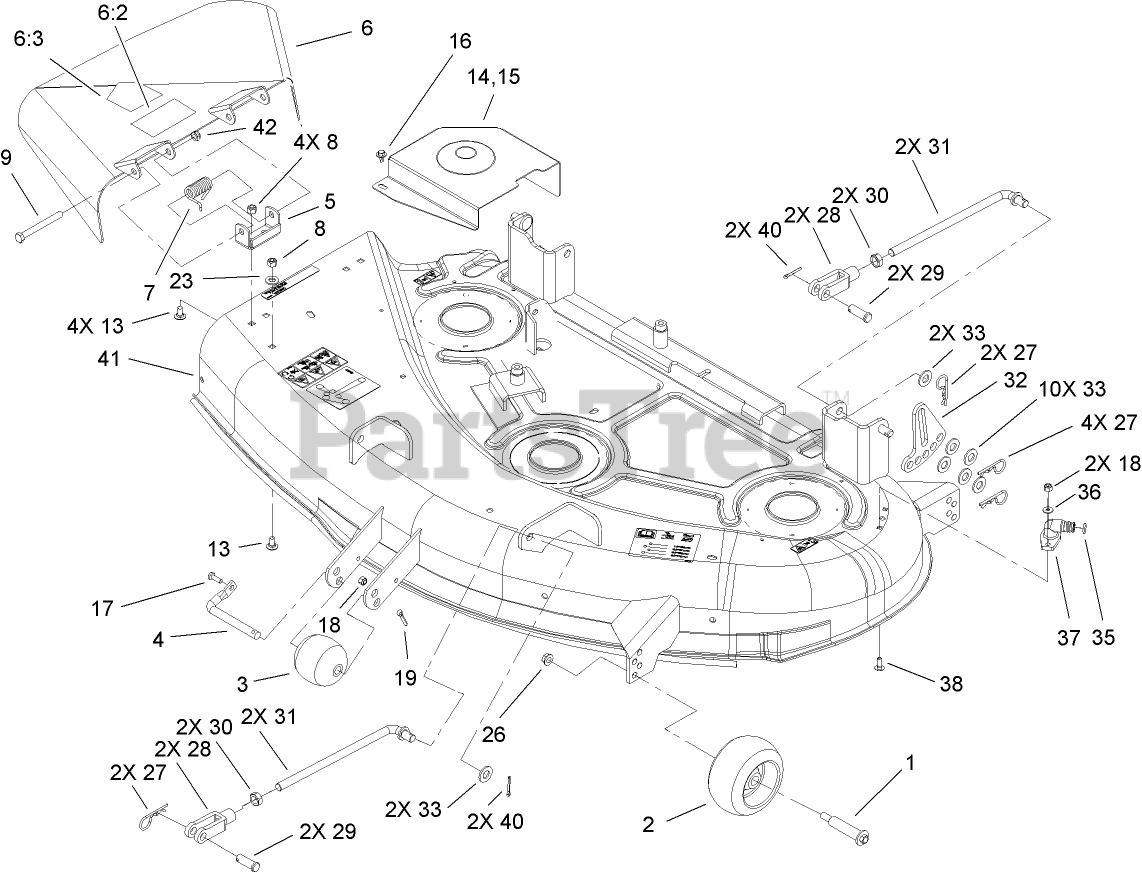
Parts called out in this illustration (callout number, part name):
1	BOLT-SHOULDER
2	ROLLER-SCALP, ANTI
3	ROLLER
4	SHAFT-ROLLER
5	BRACKET-PIVOT
6	DEFLECTOR ASM
6:2	DECAL-DANGER
6:3	DECAL-DANGER
7	SPRING
8	NUT-LOCK, NI
9	SCREW-HH
13	SCREW-CARR
15	COVER-BELT, RH
16	SCREW-HHFTF
17	SCREW-HH
18	NUT-LOCK, NI
19	PIN-COTTER
23	WASHER-FLAT
26	NUT-LOCK, NI
27	PIN-COTTER
28	CLEVIS
29	PIN-CLEVIS
30	NUT-JAM
32	LINK-HOC, ADJUSTING
33	WASHER-FLAT
35	O-RING
36	WASHER-FLAT
38	BOLT-CARR
40	PIN-COTTER
41	44 INCH DECK ASM
42	NUT-HEX
